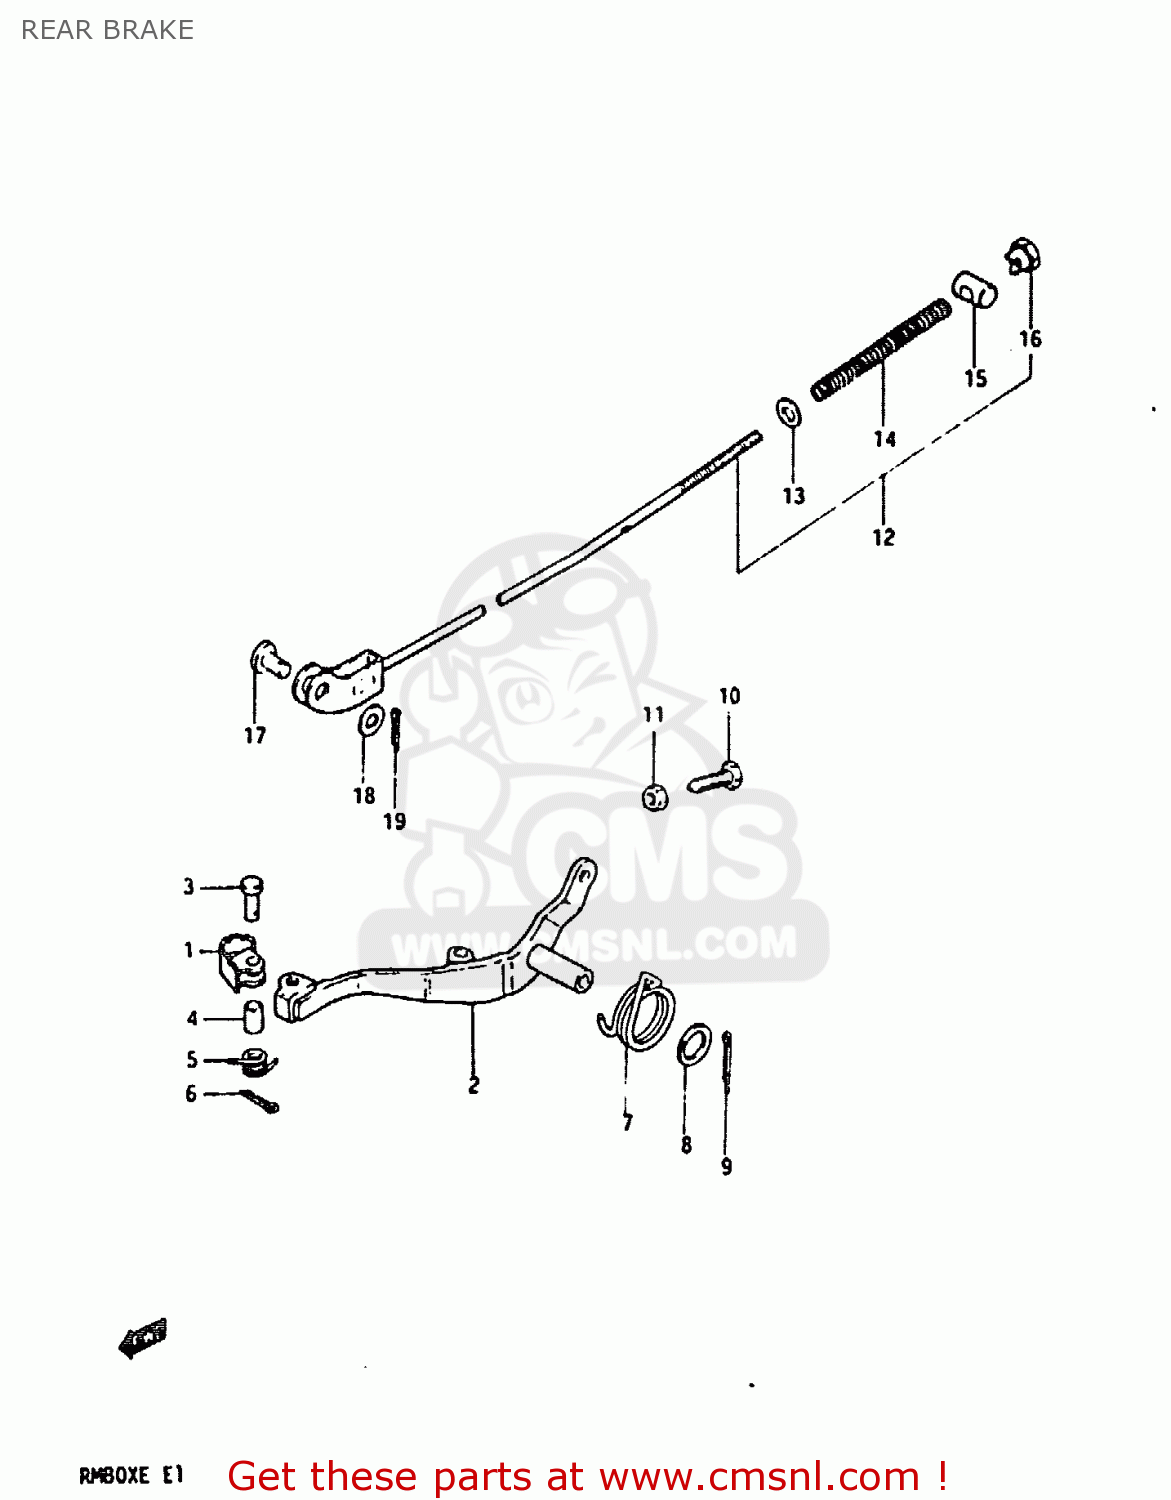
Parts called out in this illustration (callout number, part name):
1	PEDAL,BRAKE
2	ARM,BRAKE PEDAL
3	PIN
4	SPACER(6.5X10.5X6.5)
5	SPRING
6	PIN
7	SPRING
8	WASHER(15.5X26X2.3)
9	COTTER PIN
10	SCREW(6X23)
11	NUT
12	ROD ASSEMBLY,REAR BRAKE
13	WASHER
14	SPRING
15	PIN(11X18)
16	NUT (6MM)
17	PIN
18	WASHER
19	PIN 20X20
